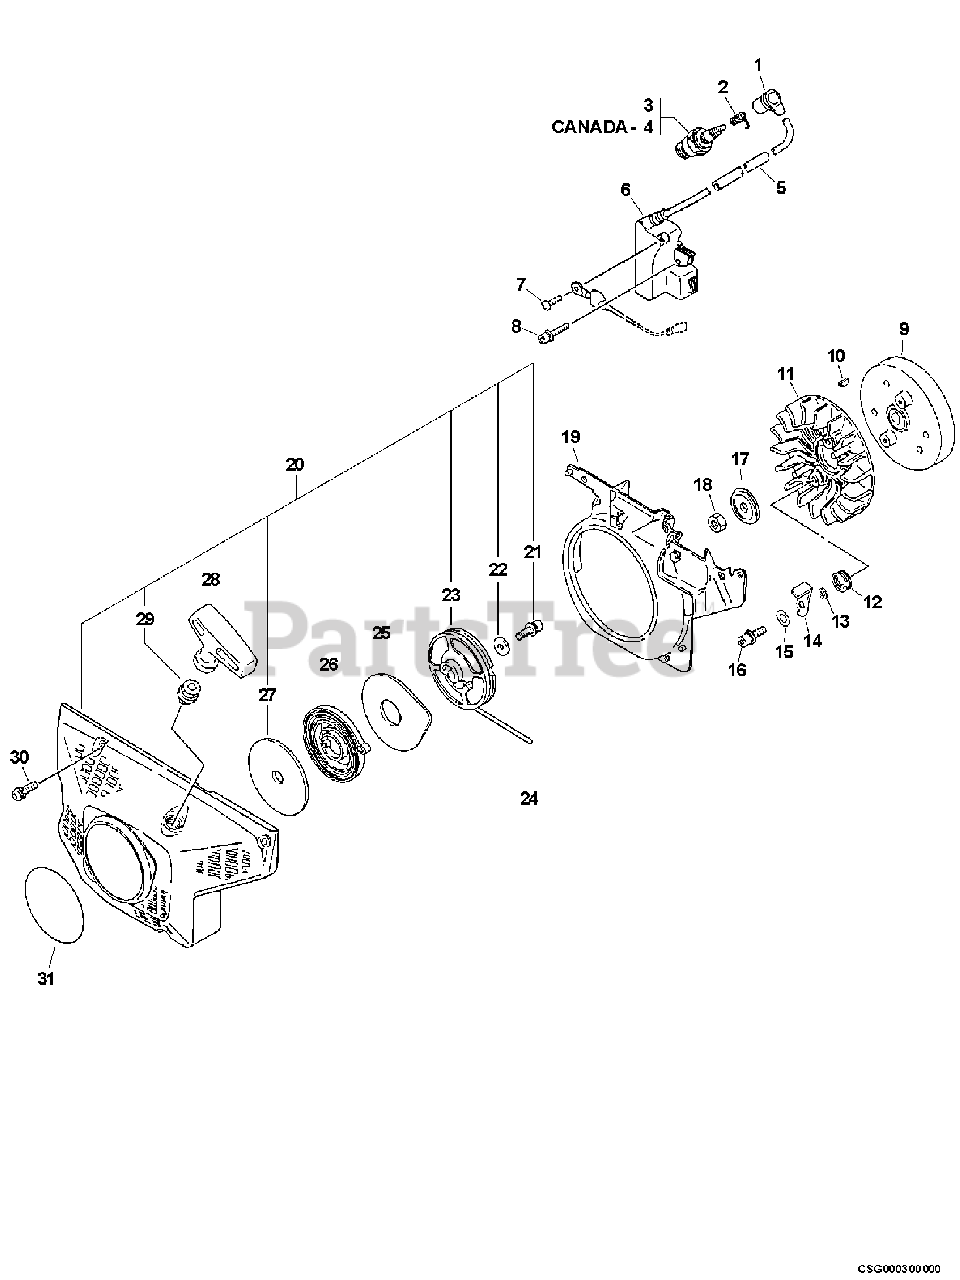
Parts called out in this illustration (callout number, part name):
1	CAP, SPARK PLUG
2	TERMINAL, SPARK PLUG CAP
3	SPARK PLUG -- BPM-6A
4	SPARK PLUG -- RCJ-8Y
6	COIL, IGNITION
7	SCREW - 4X8
8	SCREW - 4X20
9	FLYWHEEL
12	SPRING, RETURN
13	SPACER, PAWL
14	PAWL, STARTER
15	WASHER - 5
16	SCREW - 5X20
17	WASHER - CUP
19	SHIELD, FAN
20	STARTER ASSY
21	SCREW - 5X14
22	WASHER - 5
23	REEL, ROPE
24	ROPE, STARTER - 4X900
25	PLATE, STARTER
26	SPRING, REWIND
27	PLATE, STARTER
28	GRIP, STARTER
29	GUIDE, ROPE
30	SCREW - 5X20
31	LABEL - ECHO
